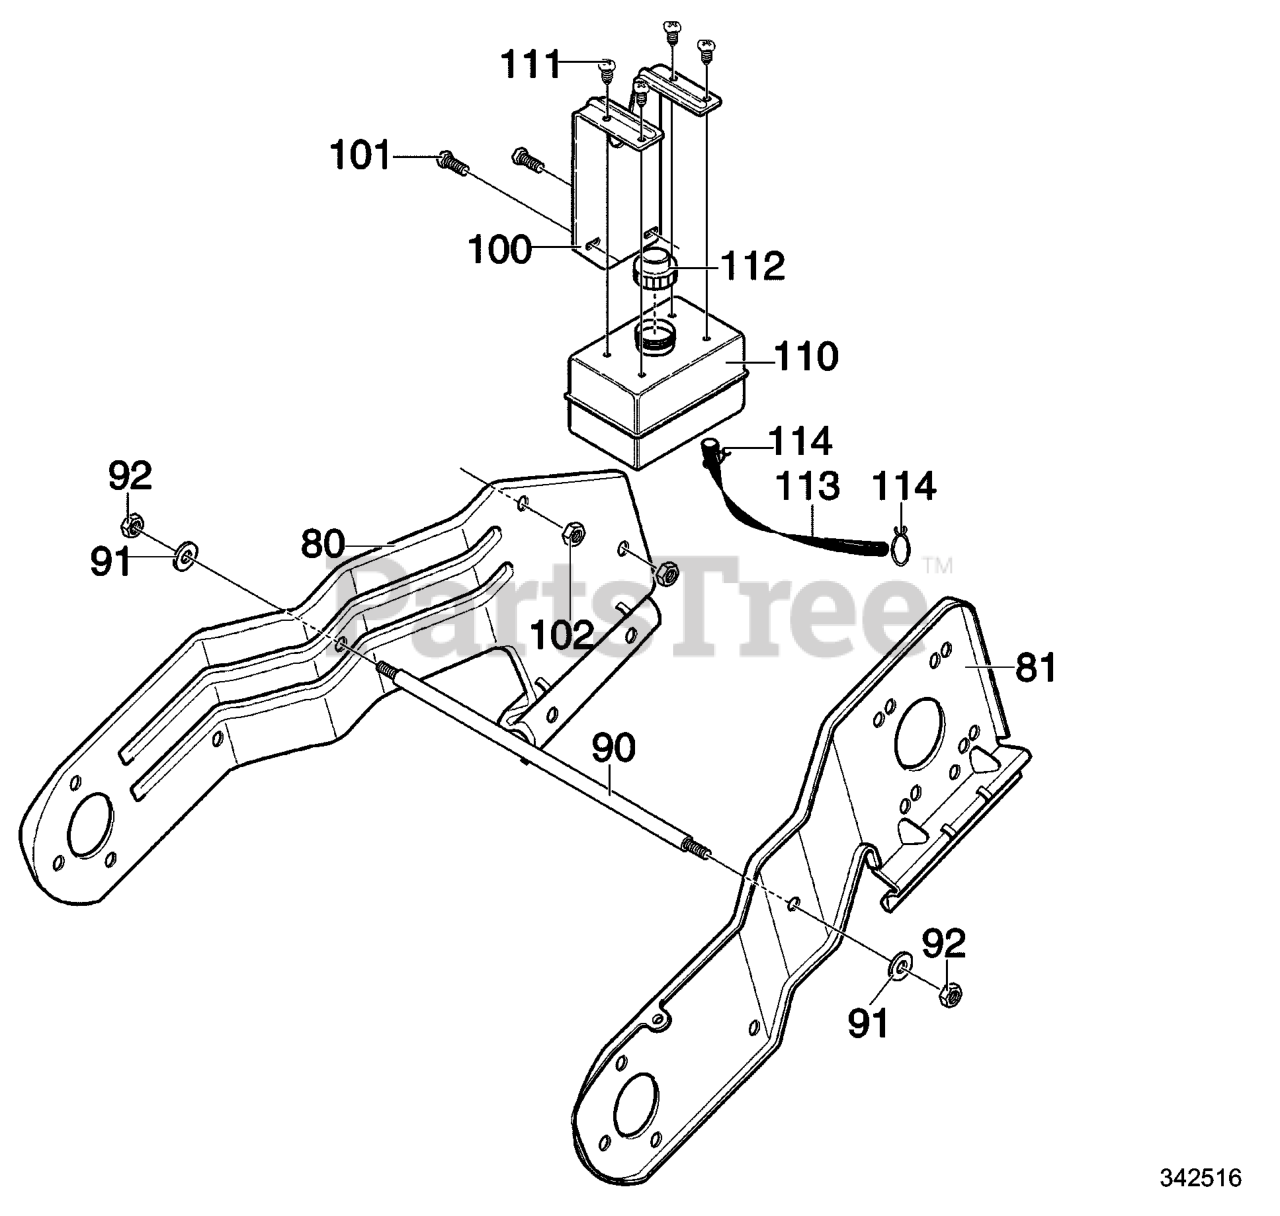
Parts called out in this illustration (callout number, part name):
80	FRAME SIDE SUPPORT RH
81	FRAME SIDE SUPPORT LH
90	ROD, SUPPORT
91	WASHER
92	NUT, 3/8-16 HEX
100	BRACKET, GAS TANK
101	SCREW, 1/4-20X.75
102	NUT, 1/4-20
110	TANK, FUEL
111	SCREW, 1/4-14X.88
112	CAP, GAS-RED
113	TUBING 11.50 IN.
114	CLAMP, FUEL LINE
